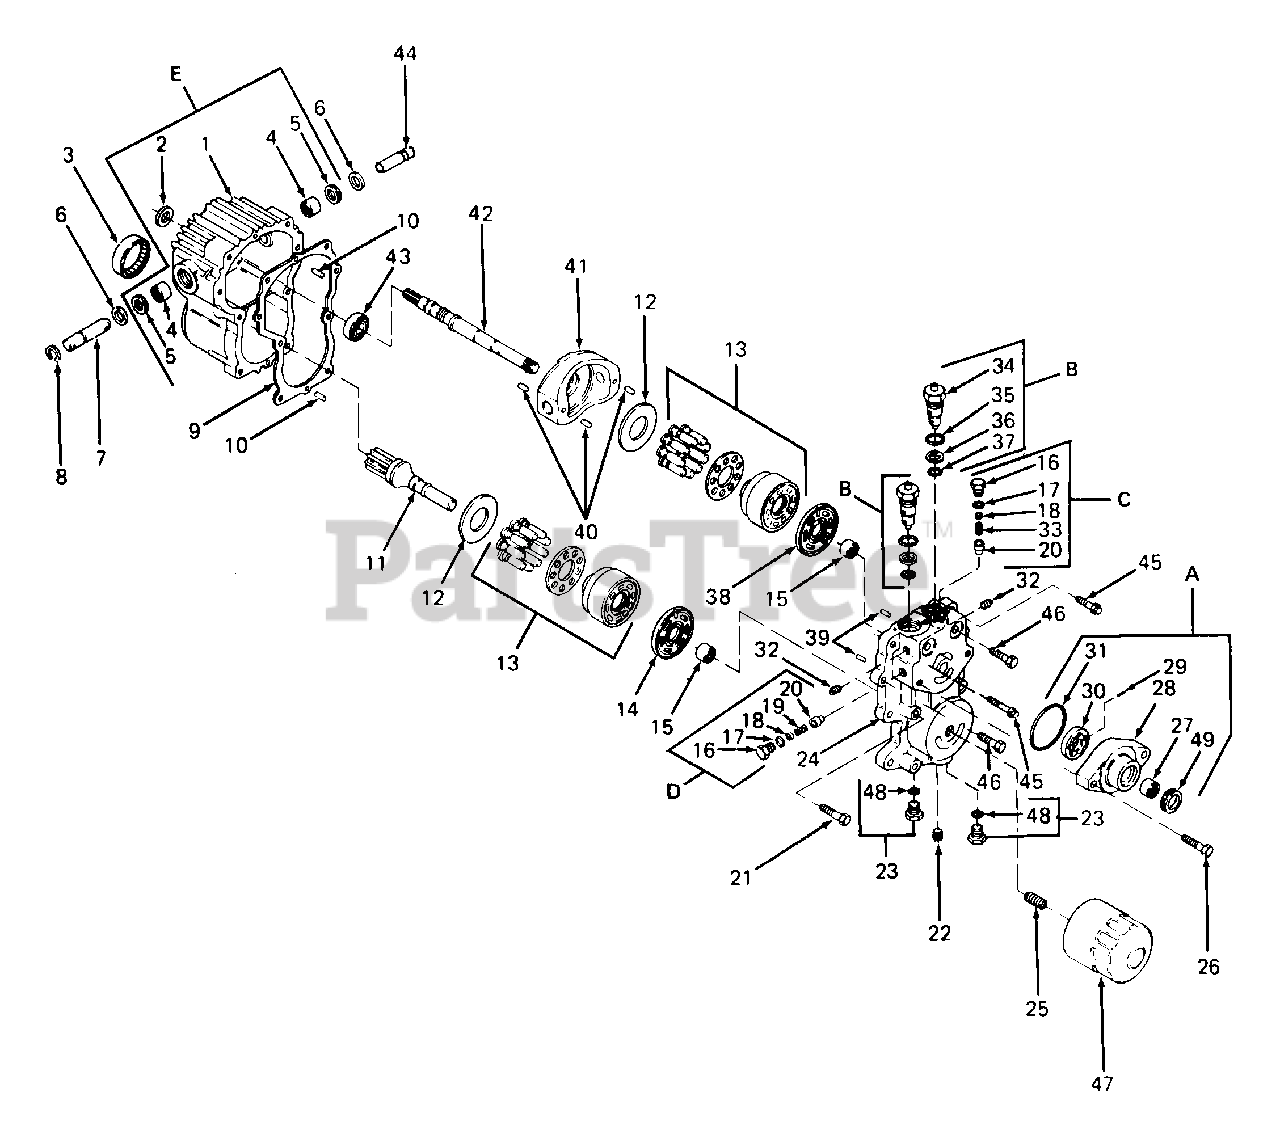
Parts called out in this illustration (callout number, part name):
1	Housing, Transmission
2	Seal, Lip
3	Bearing, Roller
4	Bearing, Needle
5	Seal, Lip
7	Shaft, Trunnion
8	Ring, Retaining
9	Gasket
10	Pin
11	Shaft, Motor
12	Plate, Thrust
13	Block, Cylinder
14	Plate, Valve
15	Bearing, Roller
16	Plug
17	O-Ring
18	Kit, Shim Pack
19	Spring, Center Relief Valve
20	Cone, Relief Valve
24	Center Section
27	Bearing, Needle
28	Charge Pump Housing
30	Gerotor
33	Spring, Implement Relief
34	Valve
36	Ring, Back-up
38	Plate, Valve
42	Shaft, Pump
44	Shaft Assembly, Trunnion
45	Screw, 12 Point
47	Oil Filter
49	Seal, Lip
A	Kit, Charge Pump
B	Valve Assembly
C	Kit, Relief Valve
D	Kit, Relief Valve
E	Housing Assembly
